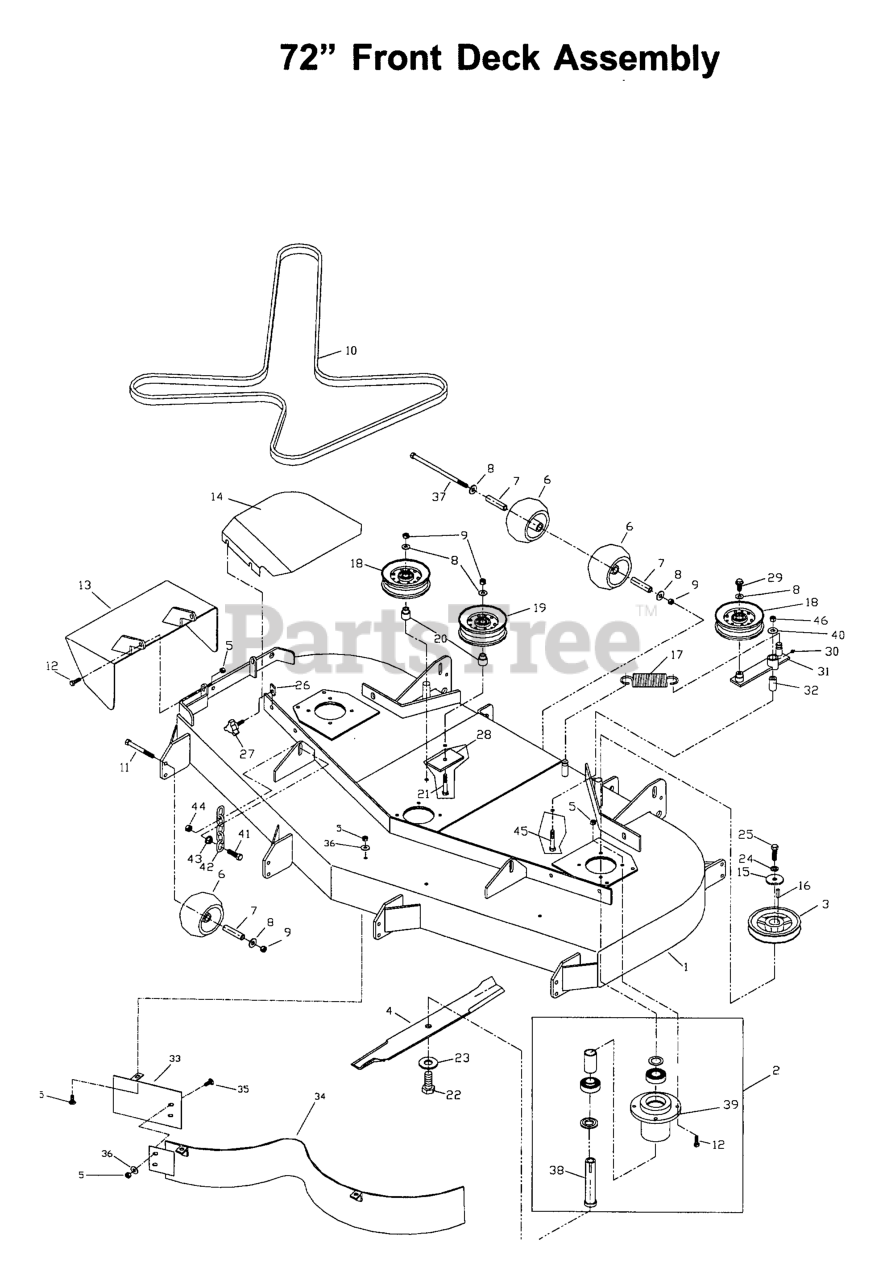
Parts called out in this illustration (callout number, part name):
1	DECK W/DECALS 72" HUS WSL
2	HOUSING KIT FOR 105632
4	BLADE OEM - 25"
5	NUT 5/16C CENTERLOCK
6	ANTI-SCALP ROLLER
8	WASHER 3/8 FLAT
9	NUT 3/8C CENTERBLOCK
10	BELT, DECK 72"
11	HCS 3/8C X 3 1/2
12	HCS 5/16C X 1 1/4
13	DISCHARGE CHUTE
14	BELT SHIELD RH ORANGE
15	SPINDLE WASHER
16	KEY 1/4 SQ X 1 1/8
17	DECK SPRING
18	IDLER PULLEY
19	IDLER PULLEY (TALL)
20	IDLER BUSHING
21	HCS 3/8C X 3
22	HEX SCREW-5/8F X 2 GR8
23	BELLEVILLE SPRING WASHER
24	WASHER 7/16 LOCK
25	HCS 7/16F X 1 1/2
26	U-CLIP 5/16-18 NUT RETAINER
27	KNOB W/STUD
28	SUPPORT PLATE
29	4CS 3/8C X 1 SERRATED HEAD
30	ZERK
32	PIVOT BUSHING
33	BAFFLE/CENTER-FLAT BLK
34	BAFFLE/CENTER-CURVED
35	CARRIAGE BOLT 5/16C X 5/8"
36	WASHER 5/16 FLAT
37	BOLT 3/8 X 6" GRD 8
38	SPINDLE SHAFT
39	HOUSING, DIE CAST
40	WASHER 1/2 FLAT
41	HCS 7/16C X 1 1/2
42	LIFT CHAIN
43	NUT 7/16C WHIZ
44	NUT 7/16C CENTERLOCK
45	HCS 1/2C X 3 1/4
46	NUT 1/2-13 HEX NYLOC ZD
539105566	BELT SHIELD LH ORANGE
539107406	BEARING KIT
